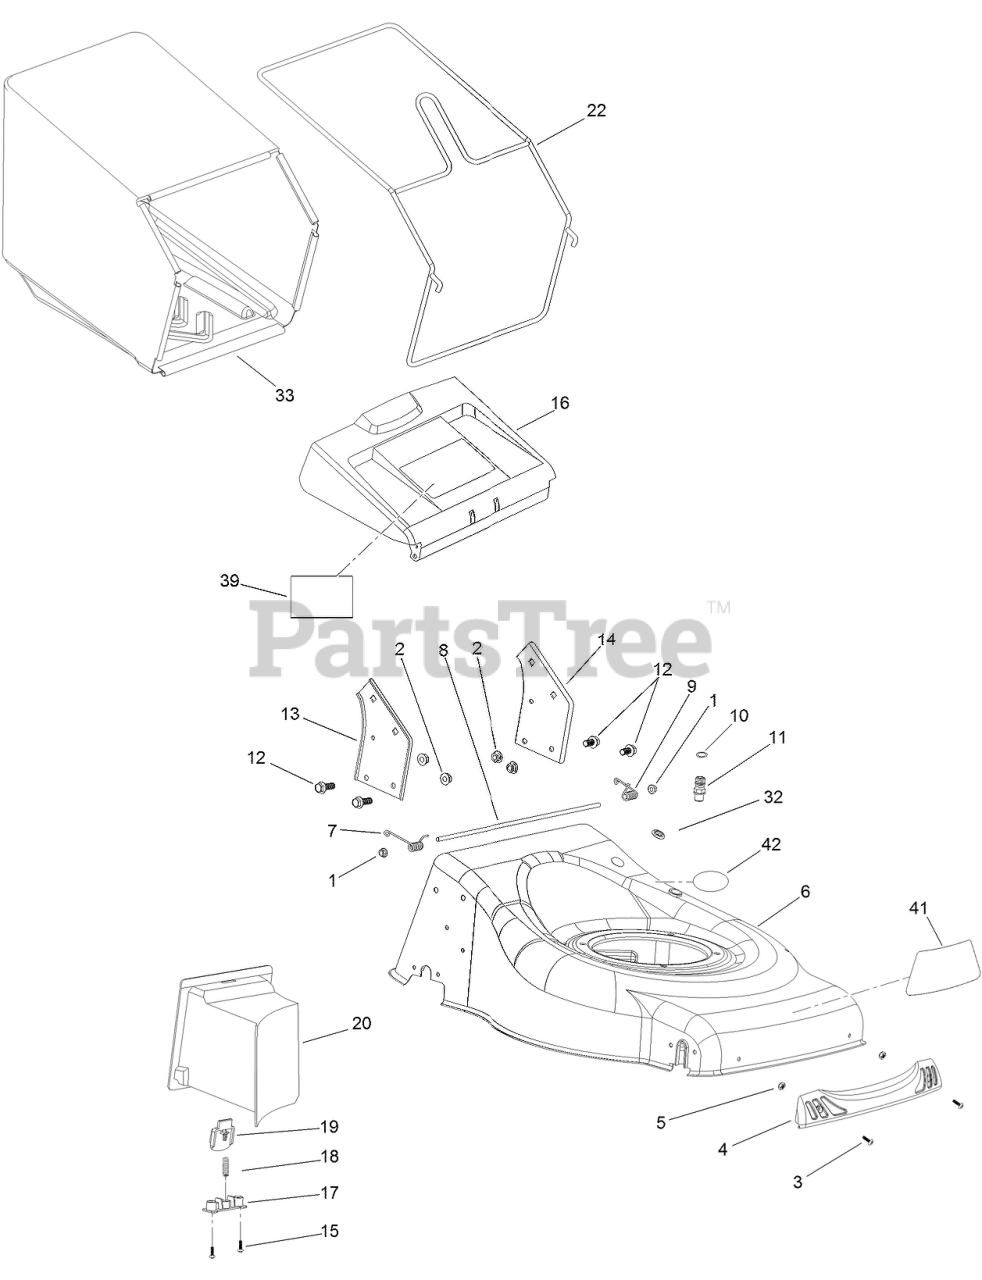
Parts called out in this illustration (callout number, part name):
1	NUT-LOCK, FLANGE
2	NUT-LOCK, FLANGE
3	SCREW-TOOTH
4	BUMPER-FRONT
5	NUT-LOCK
7	SPRING-TWIST, RH
8	ROD-SPRING, REAR DEFLECTOR
9	SPRING-TWIST, LH
10	O-RING
11	PORT-WASH
12	BOLT-HH, FLANGE
13	BRACKET-HANDLE, RH
14	BRACKET-HANDLE, LH
15	SCREW-SELF DRIVING
16	DEFLECTOR-REAR
17	PRESSING BOARD-LOCK BUTTON, MULCH
18	SPRING-BUTTON, MULCH
19	LOCK-BUTTON, MULCH
20	PLUG-MULCH
22	FRAME-BAG, GRASS
32	SHEATH-CABLE, PROTECTIVE
33	BAG-GRASS
39	DECAL-SAFETY
41	DECAL-SHROUD
42	DECAL-PORT, WASHOUT
